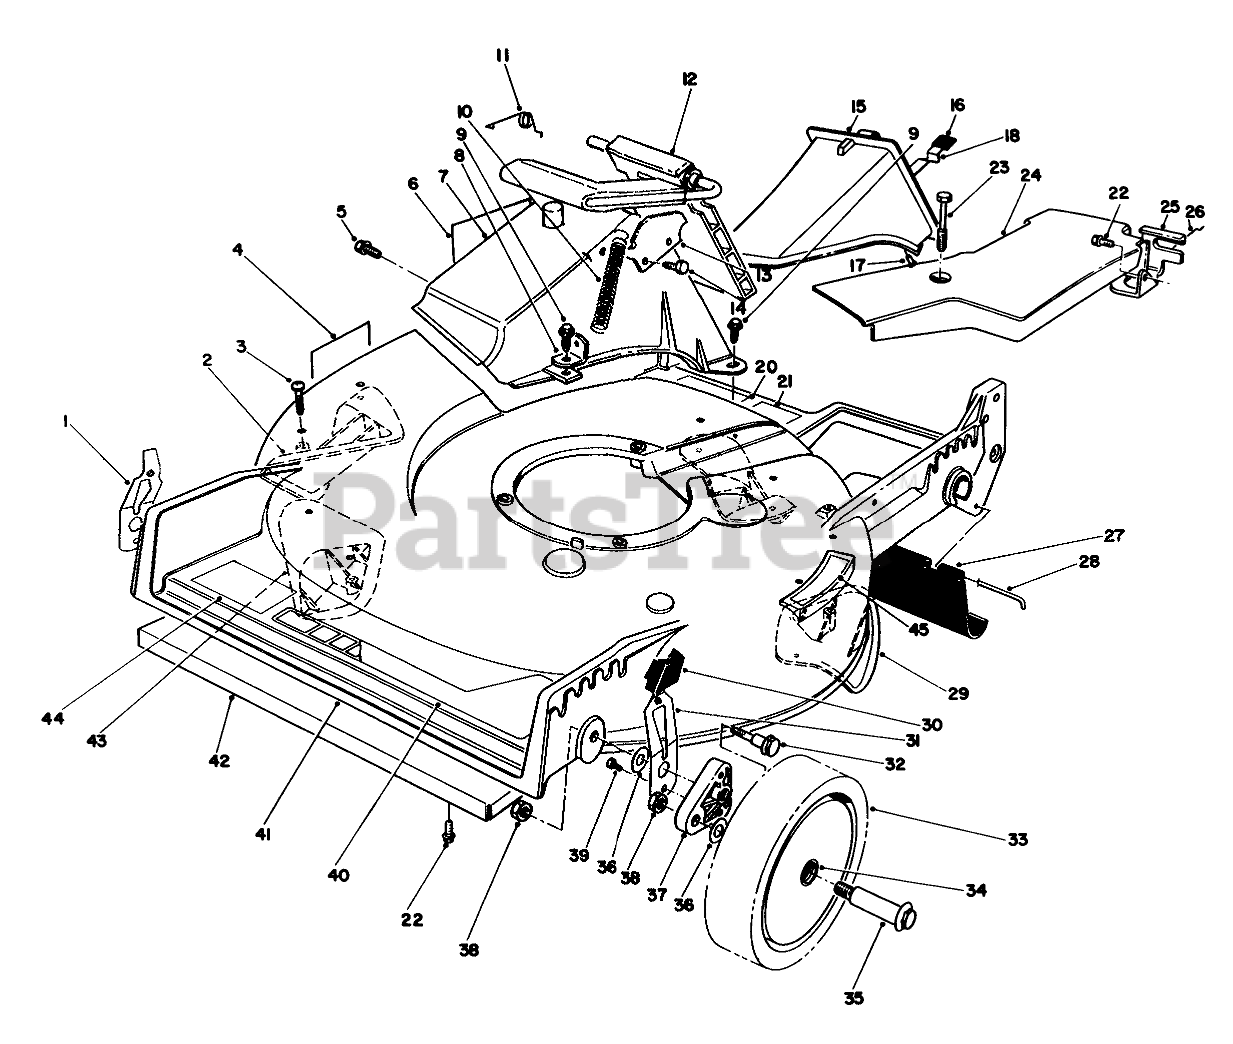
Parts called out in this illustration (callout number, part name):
1	RH SPRING ARM ASSEMBLY
2	KICKER
3	SCREW-PPH
4	Decal Danger
5	SCREW AND WASHER ASM
6	DECAL - DANGER
7	Tunnel-Discharge (Incl. Ref. #6)
8	Bracket-Spring
9	SCREW-HWH
10	SPRING-DOOR
11	RETAINER-DOOR
12	DOOR ASSEMBLY
13	DOOR LATCH PLATE
14	SCREW-PLASTITE
15	Plug Assembly (Incl . Ref. #16-18)
16	GRIP-LATCH
17	RIVET-HEAD, FLAT
18	LATCH-PLUG, DISCHARGE
19	KICKER
20	DECAL FRENCH REGUL.
21	Decal-Noise
22	SCREW-HWHTF
23	SCREW-HHFTF
24	BELT COVER
25	Bracket-Adj. Trac
26	RETAINER-CABLE
27	SHIELD-TRAILING
28	ROD-SHIELD
29	KICKER
30	KNOB-ARM
31	LH SPRING ARM ASSEMBLY
32	SCREW-SHOULDER
33	Wheel & Tire Assembly (Incl. Ref. #34)
34	BUSHING
35	WHEEL BOLT
36	WASHER
37	ARM-PIVOT, FRONT
38	Nut
39	SCREW-HWH
40	DECAL - DECK
41	Housing Assembly (Incl. Ref. #2-4, 19, 29 & 43)
42	Shield-front
43	KICKER
44	DECAL
45	DECAL - STEP PAD INT'L
